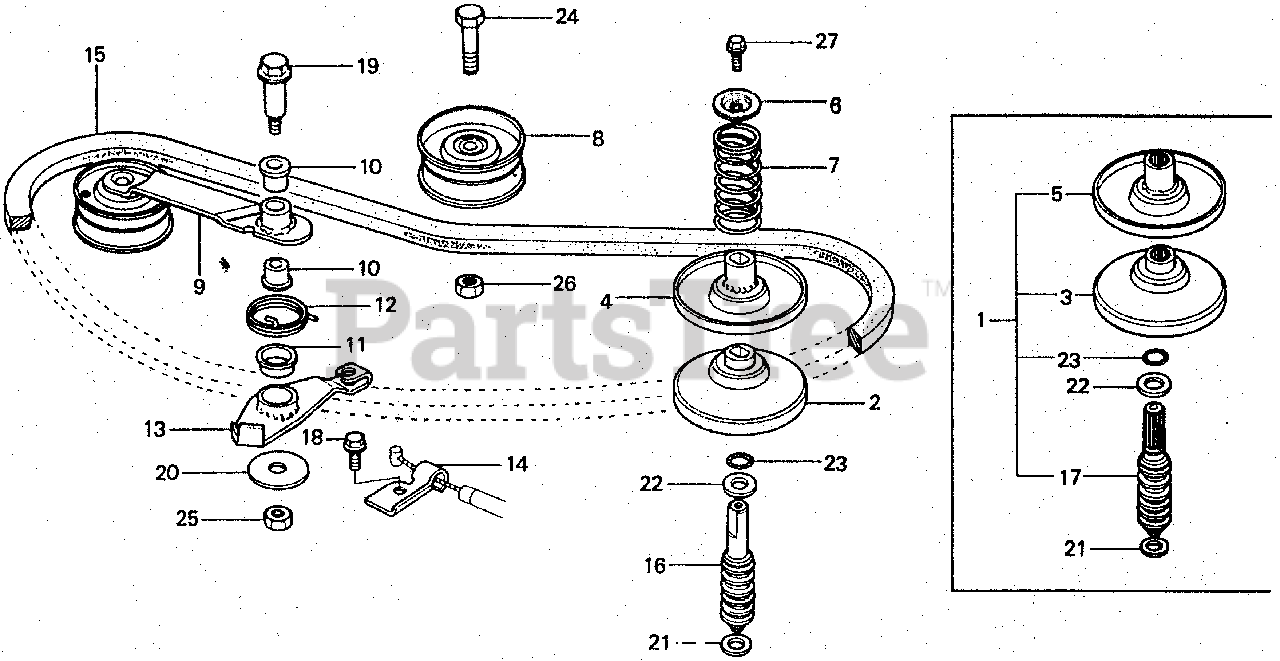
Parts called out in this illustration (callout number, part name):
1	PULLEY KIT, DRIVE
2	FACE, DRIVEN
3	FACE, DRIVEN
4	FACE, MOVABLE DRIVEN
5	FACE, MOVABLE DRIVEN (NOT AVAILABLE)
6	SEAT, SPRING
7	SPRING, DRIVEN FACE
8	ROLLER
9	ARM, TENSIONER
10	BUSH, TENSIONER ARM
11	BUSH, CHANGE ARM
12	SPRING, TENSIONER ARM (NOT AVAILABLE)
13	ARM, CHANGE (NOT AVAILABLE)
14	HOLDER, CHANGE WIRE (NOT AVAILABLE)
15	V-BELT (35)
16	PULLEY KIT, DRIVE
16	GEAR, DRIVE
17	GEAR, DRIVE
18	BOLT, FLANGE (6X12) (CT200)
19	BOLT, TENSIONER ARM
20	WASHER, PLAIN (8MM) (NOT AVAILABLE)
21	WASHER (8MM) (NOT AVAILABLE)
22	WASHER, THRUST (12MM)
23	O-RING (11.7X1.2)
24	BOLT, HEX. (10X28)
25	NUT, HEX. (8MM)
26	NUT, HEX. (10MM)
27	BOLT, FLANGE (6X12)
